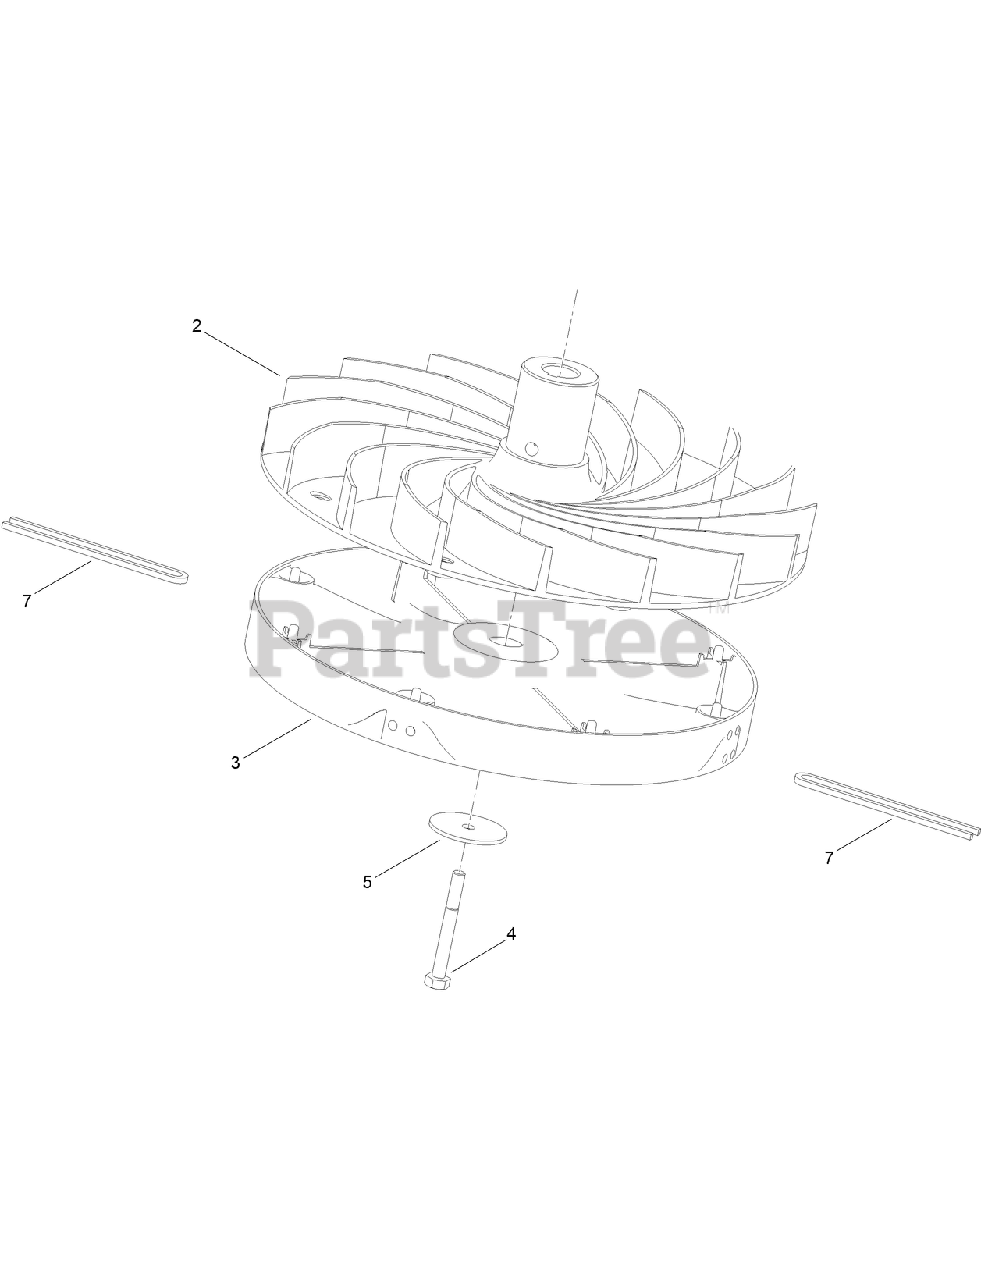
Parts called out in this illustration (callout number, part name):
2	IMPELLER
3	DISC-CUTTING
4	BOLT-HH
5	DISC-SPRING
7	LINE-CUTTING, NYLON (27M SPOOL)
